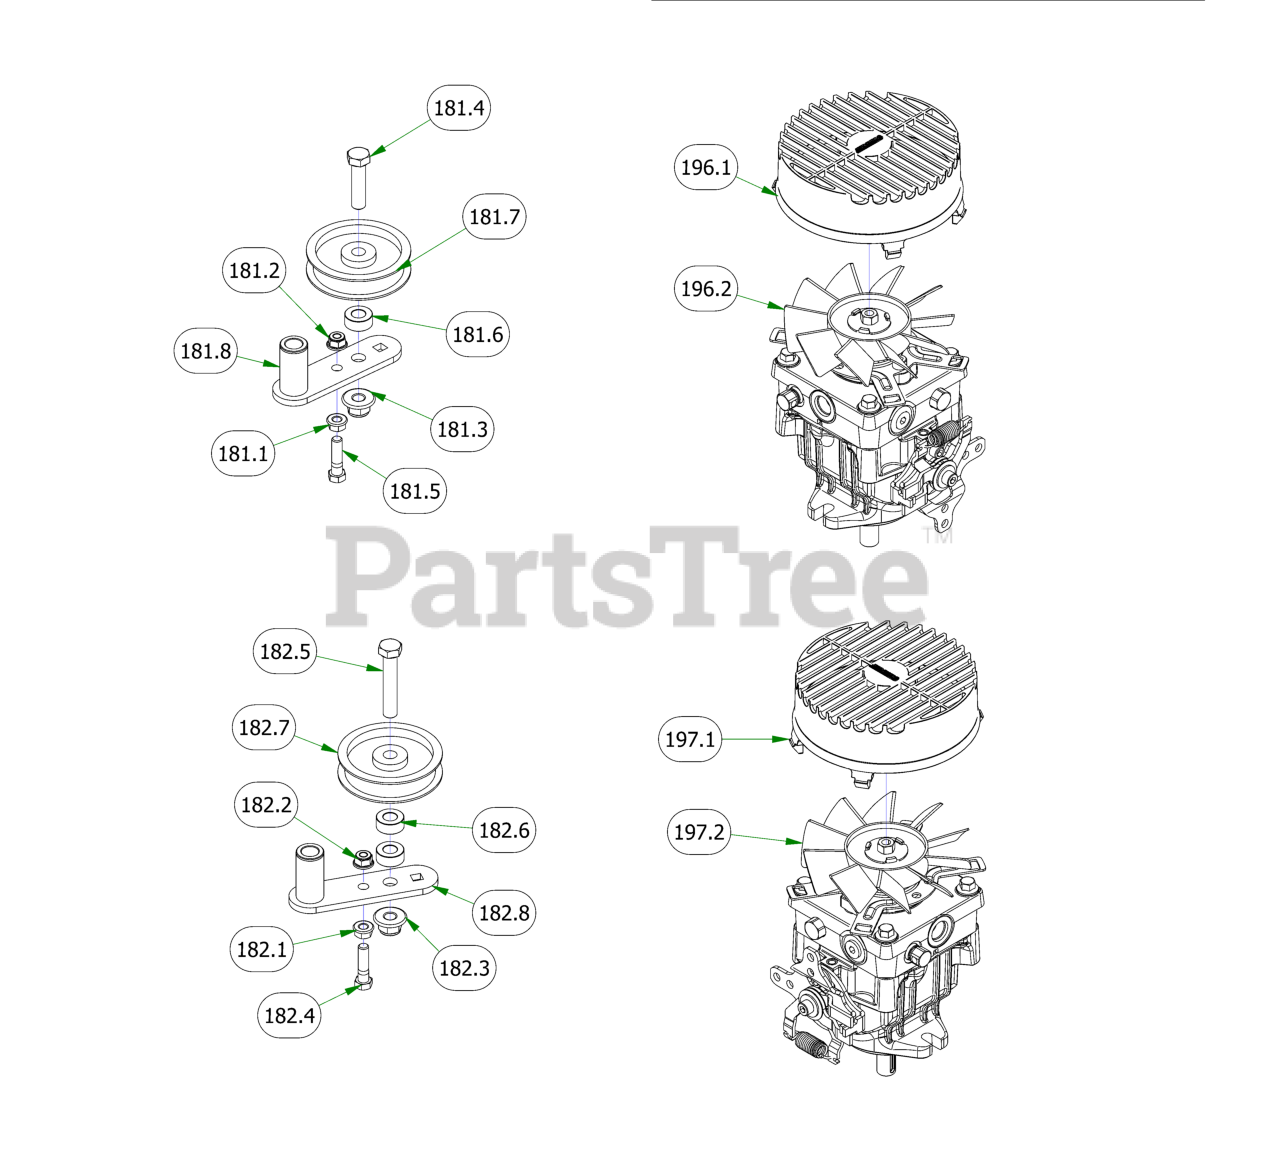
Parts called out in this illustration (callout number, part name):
181	2019 Renegade Belt Tensioner LH
181.1	3/8" Flange Nut
181.2	3/8" Nylock Flange Nut
181.3	1/2-13 Nylon Flange Nut
181.4	1/2-13x2 Grade 8 Hex Bolt
181.5	3/8" x 1 1/2" Hex Bolt
181.6	1/2 Solid Shaft Collar (W/1 Set Screw) Zinc
181.7	3.25 Flat Idler Pulley
181.8	Horizontal Idler Arm with Bushings
182	2019 Renegade Pump Belt Tensioner RH
182.1	3/8" Flange Nut
182.2	3/8" Nylock Flange Nut
182.3	1/2-13 Nylon Flange Nut
182.4	3/8" x 1 1/2" Hex Bolt
182.5	1/2" x 2 3/4" Hex Bolt
182.6	1/2 Solid Shaft Collar (W/1 Set Screw) Zinc
182.7	3.25 Flat Idler Pulley
182.8	Horizontal Idler Arm with Bushings
196	2019 Rogue/Renegade Left Pump 16cc
196.1	Fan Guard 6" - Fits Wheel
196.2	Hydro Fan - Light/Pup/Outlaw XP
197	2019 Outlaw Renegade Right Pump 16cc
197.1	Fan Guard 6" - Fits Wheel
197.2	Hydro Fan - Light/Pup/Outlaw XP
